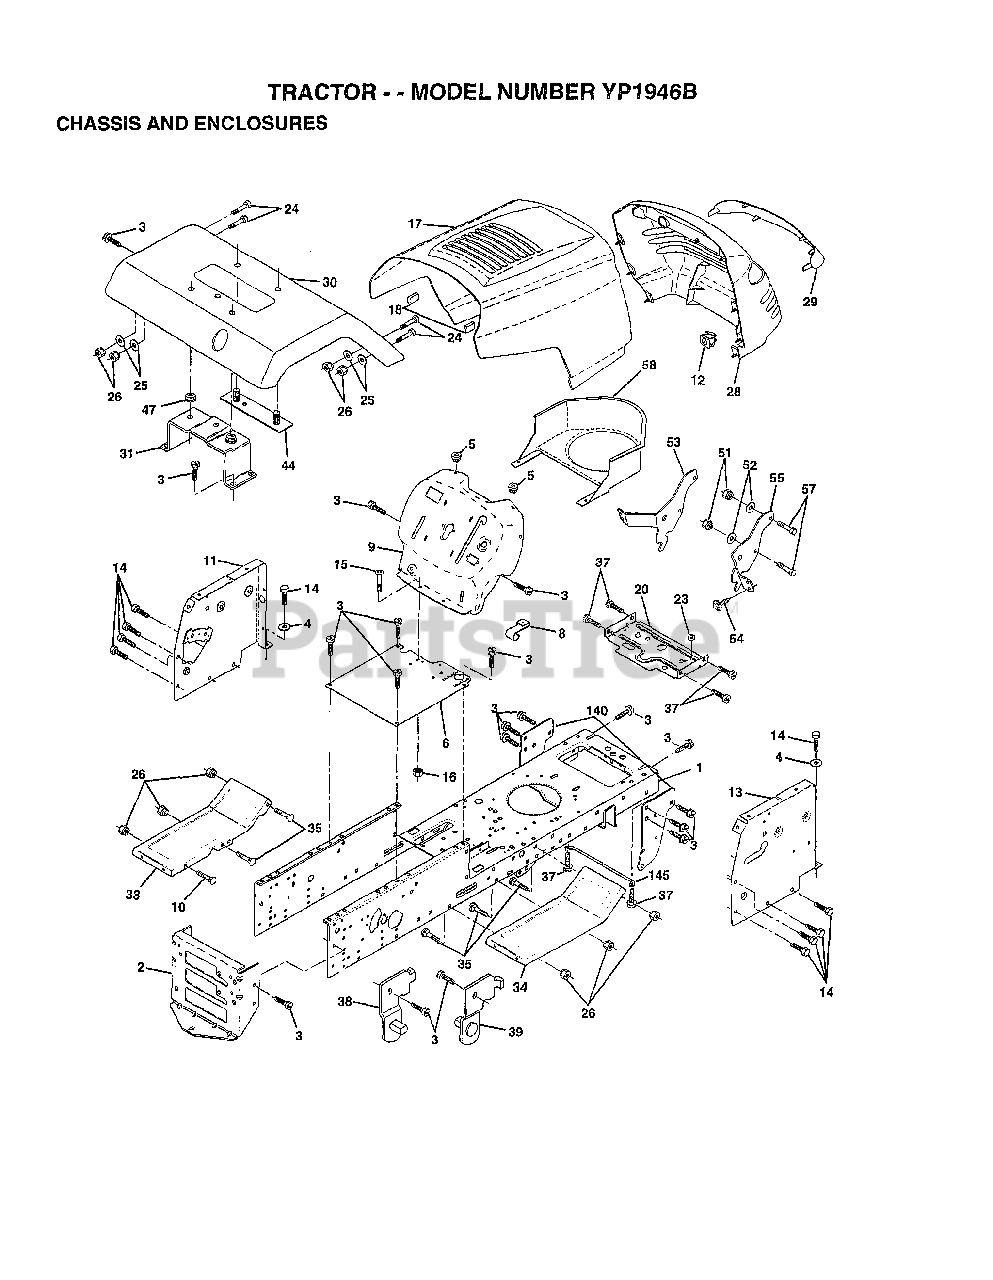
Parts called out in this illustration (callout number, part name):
3	SCREW
4	WASHER
5	BUMPER-HOOD/DASH
6	SADDLE
8	"CLIP,INSULATOR"
9	DASH.PANEL.ASSY
11	"PANEL-DASH,LH"
12	CLIP.TINNERMAN
13	"PANEL-DASH,RH"
14	SCREW LT
15	SCREW
17	"HOOD W/TRIM,MS428"
20	"PLATE-MTG,BATT/FU"
24	BOLT
25	WASHER
26	NUT
28	GRILL
29	LENS.EURO.W/DECAL
30	"FENDER WS,FTK"
31	BRKT.ASM.FENDER
33	FOOTREST PNT LH
34	FOOTREST.RH.LT/GT
35	BOLT
38	BRACKET ASM LH
39	BRACKET ASM RH
44	STRAP ASM FENDER
47	NUT-PUSH YT
51	NUT
52	WASHER
53	BRACKET.GRILLE.LH
54	SCREW.HEX.WS.HD
55	BRACKET.GRILLE.RH
58	CAP ASM FUEL
140	BRKT SUSPENSION
145	"ROD POVOT,CHASSIS"
